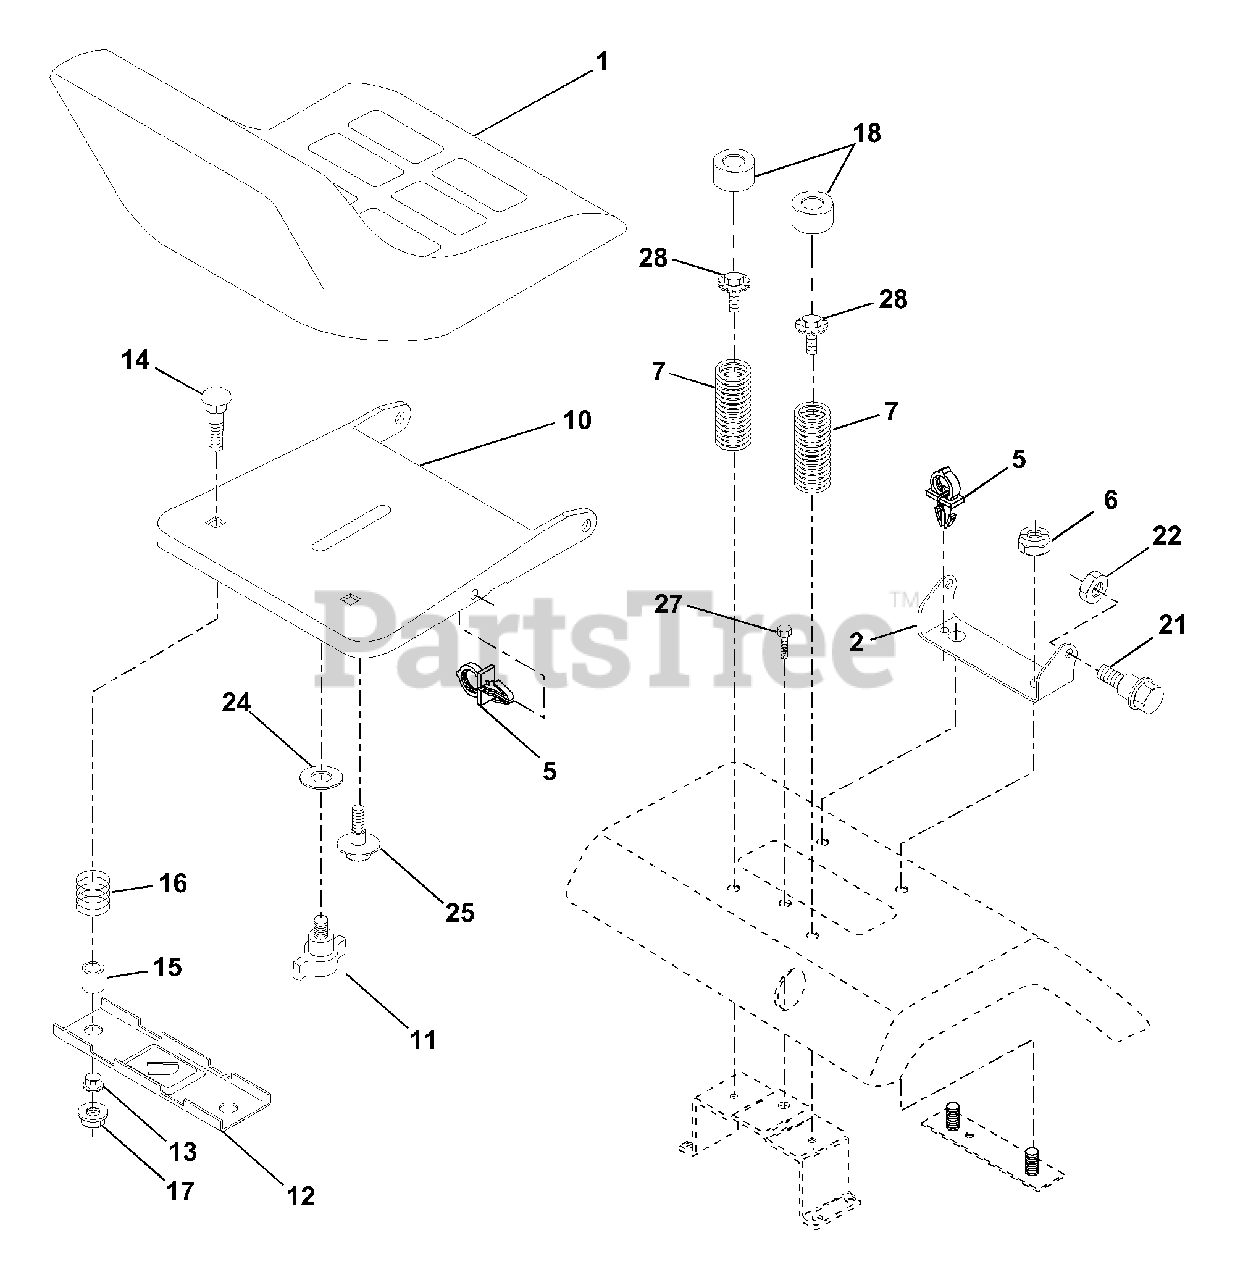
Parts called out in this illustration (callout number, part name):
2	Pivot Bracket, Seat
5	Clip, Push-in Hinged
6	Nut, Lock Hex w/Ins 3/8-16 UNC
7	Spring, Seat
10	Pan, Seat
11	Knob, Seat, Black
12	Bracket, Switch Mounting
13	Bushing, Snap, Black, Nylon
14	Bolt, Carriage 1/4-20 x 1-1/2
15	Spacer, Split
16	Spring
17	Locknut, Flange 1/4 Grade 5
18	Cap Spring Seat Blk 1.75 x 1.0
21	Bolt, Shoulder 5/16-18 Unc -2A
22	Nut Lock Hex W/Ins 5/16-18 Unc
24	Washer 17/32 x 1-3/16 x 12 Gauge
25	Bolt, Shoulder 5/16-18 x .62
27	Screw Thdrol 3/8-16 x 3/4
28	Bolt 5/16-18 UNC x 3/4 w/Sems
